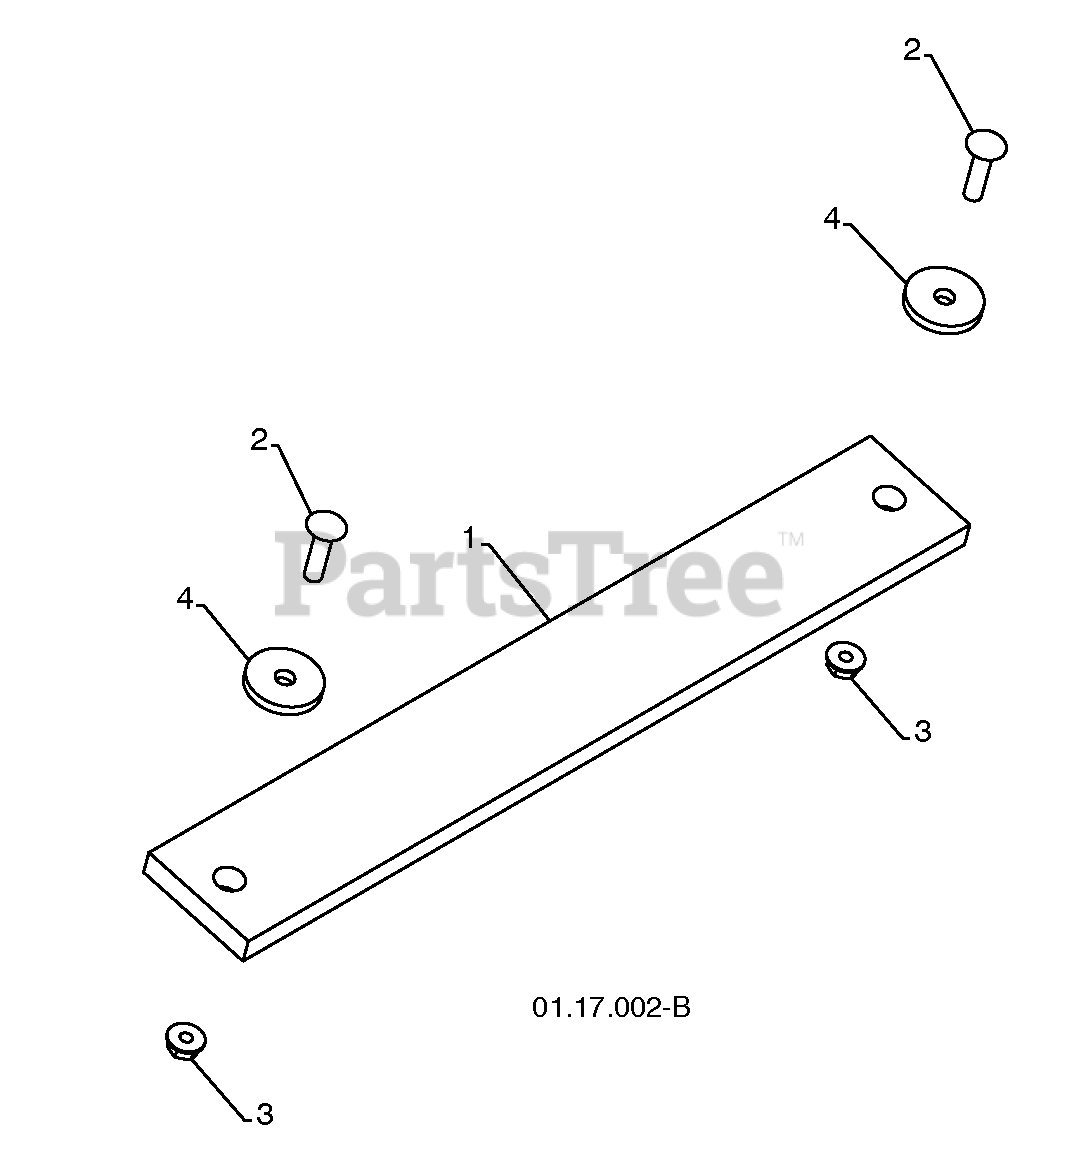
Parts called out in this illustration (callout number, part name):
1	WEIGHT BAR
2	CARRIAGE BOLT 5/16-18 X 1.25
3	NUT 5/16-18
